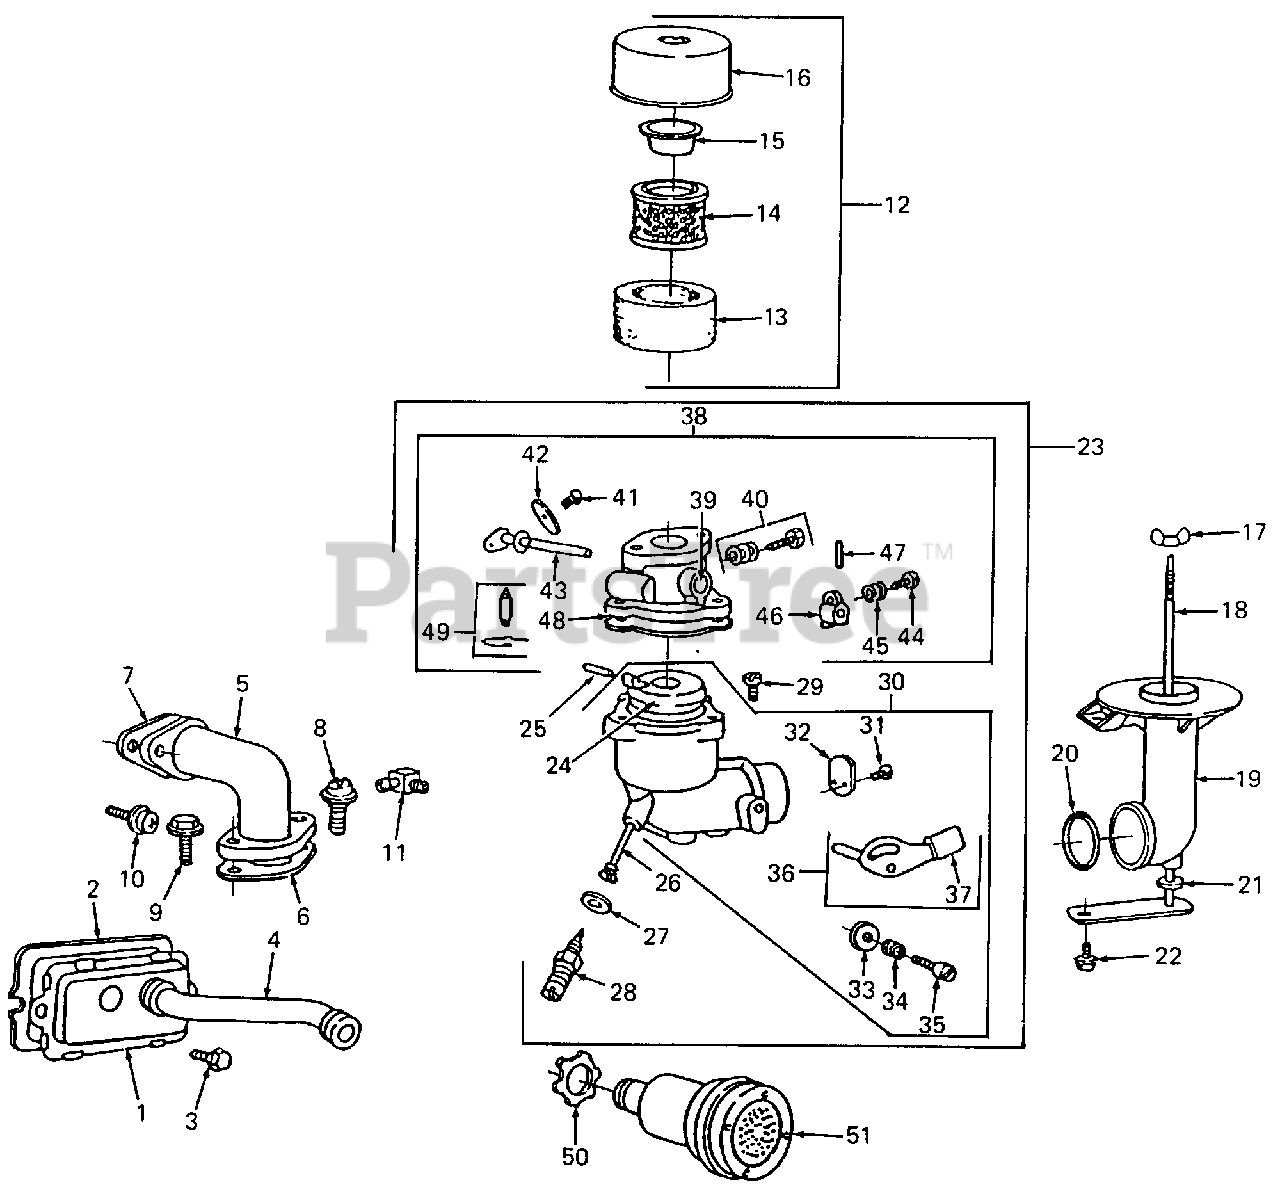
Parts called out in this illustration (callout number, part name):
1	Breather Valve Assy
2	Gasket, Valve Cover
3	Screw, Sem
4	Tube, Breather
5	Elbow, Intake
6	Gasket, Carburetor Mtg
7	Gasket, Intake Elbow Mtg
8	Screw, Shoulder
9	Screw, Sem - Carburetor Mtg
10	Screw, Sem - Intake Elbow Mtg
11	Connector, Fuel Pipe
12	Air Cleaner Assy
13	Element, Air Cleaner
14	Cartridge, Air Cleaner
15	Cup, Air Cleaner
16	Cover, Air Cleaner
17	Nut, Wing
18	Stud, Air Cleaner
19	Pipe Assy, Air Cleaner
20	O-Ring, Air Cleaner
21	Seal, Air Cleaner Stud
22	Screw, Sem
23	Carburetor Assy
24	Float, Carburetor
25	Pin, Float Hinge
26	Nozzle, Carburetor
27	Gasket, Nozzle
28	Valve, Needle
29	Screw, Sem, Hex Hd
30	Body Assy, Lower Carburetor
31	Screw, Sem, Choke Mtg
32	Valve, Choke
33	Washer, Choke Lever
34	Spring, Choke Lever
35	Screw, Choke Lever
36	Shaft & Lever, Choke
37	Sleeve, Choke Lever
38	Body Assy, Upper Carburetor
39	Bushing, Throttle Shaft
40	Valve Assy, Carburetor Idle
41	Screw, Sem, Throttle Mtg
42	Valve, Throttle
43	Shaft & Lever, Throttle
44	Screw, Fil Hd, 8-32 X 5/8
45	Spring, Throttle Adjustment
46	Stop, Throttle
47	Pin, Throttle, Stop
48	Gasket, Carburetor
49	Valve, Fuel Inlet
50	Lock Nut, Muffler
51	Muffler
